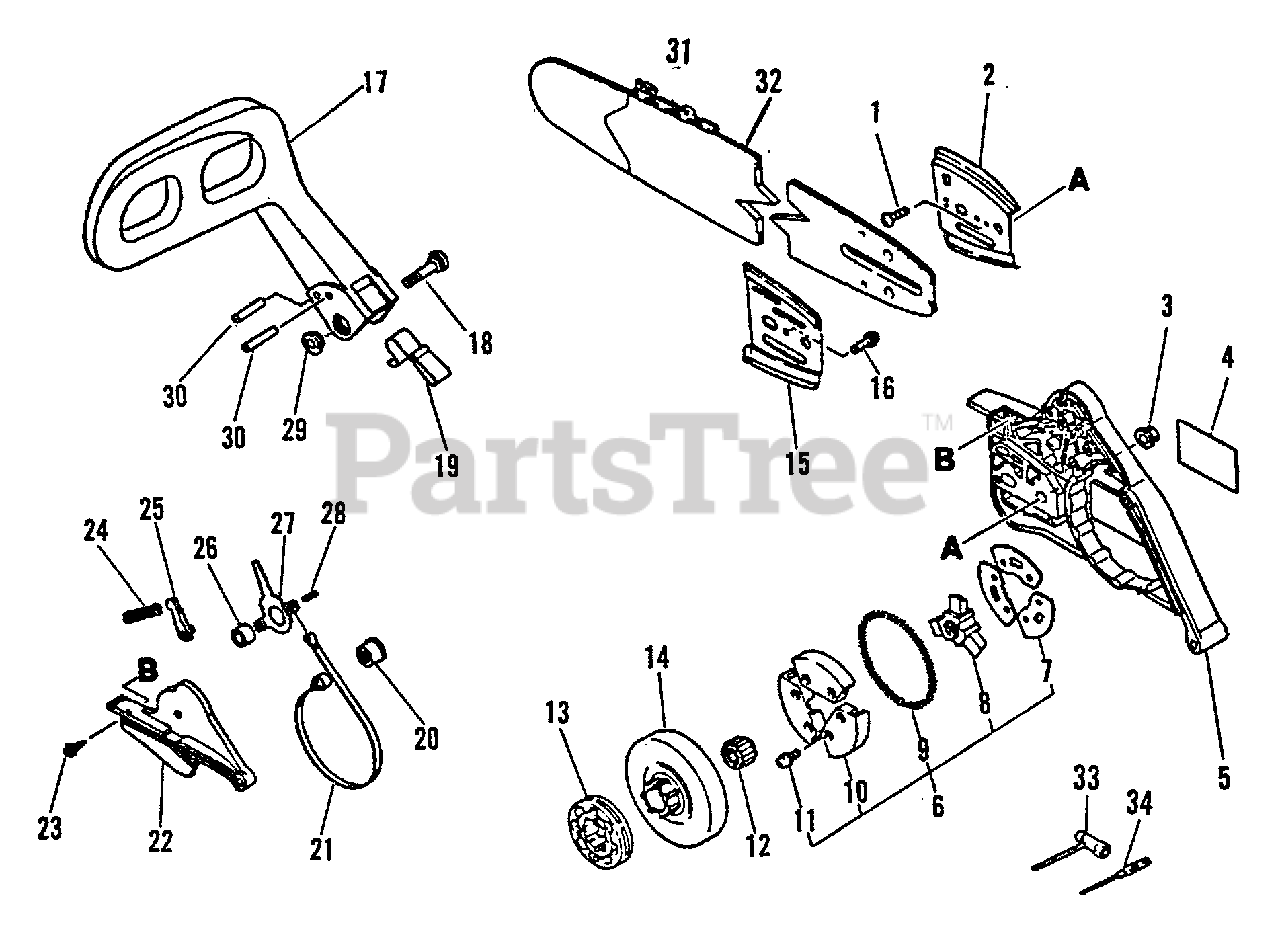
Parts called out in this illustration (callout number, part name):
1	SCREW 4×8
2	PLATE, GUIDE
3	NUT, FLANGE M8×1.25
4	LABEL - ECHO
5	GUARD, SPROCKET
6	CLUTCH ASSY
7	PLATE, CLUTCH
8	HUB, CLUTCH
9	SPRING, CLUTCH
10	SHOE SET, CLUTCH (3PCS)
11	BOLT 4×6
12	BEARING, NEEDLE
13	SPROCKET, 0.325 RIM
14	DRUM, CLUTCH
15	PLATE, GUIDE
16	SCREW 3×6
17	LEVER, BRAKE
18	MOUNTING KIT
19	SPRING, RETURN
20	ADJUSTER, BRAKE
21	BAND, BRAKE
22	COVER, BRAKE
23	SCREW 4×10
24	SPRING, COMPRESSION
25	STOPPER, BRAKE
26	SPACER 8×12×9
27	LEVER, BRAKE
28	PIN, SPRING - 4×8
30	PIN 3.5×26
31	SAWING CHAIN - 16" -- PRO GUARD
31	SAWING CHAIN - 18" -- PRO GUARD
31	SAWING CHAIN - 20" -- PRO GUARD
32	GUIDE BAR - 16" -- DOUBLE GUARD
32	GUIDE BAR - 18" -- DOUBLE GUARD
32	GUIDE BAR - 20" -- DOUBLE GUARD
33	T-WRENCH 13×19×180
34	SCREWDRIVER, PHILLIPS
